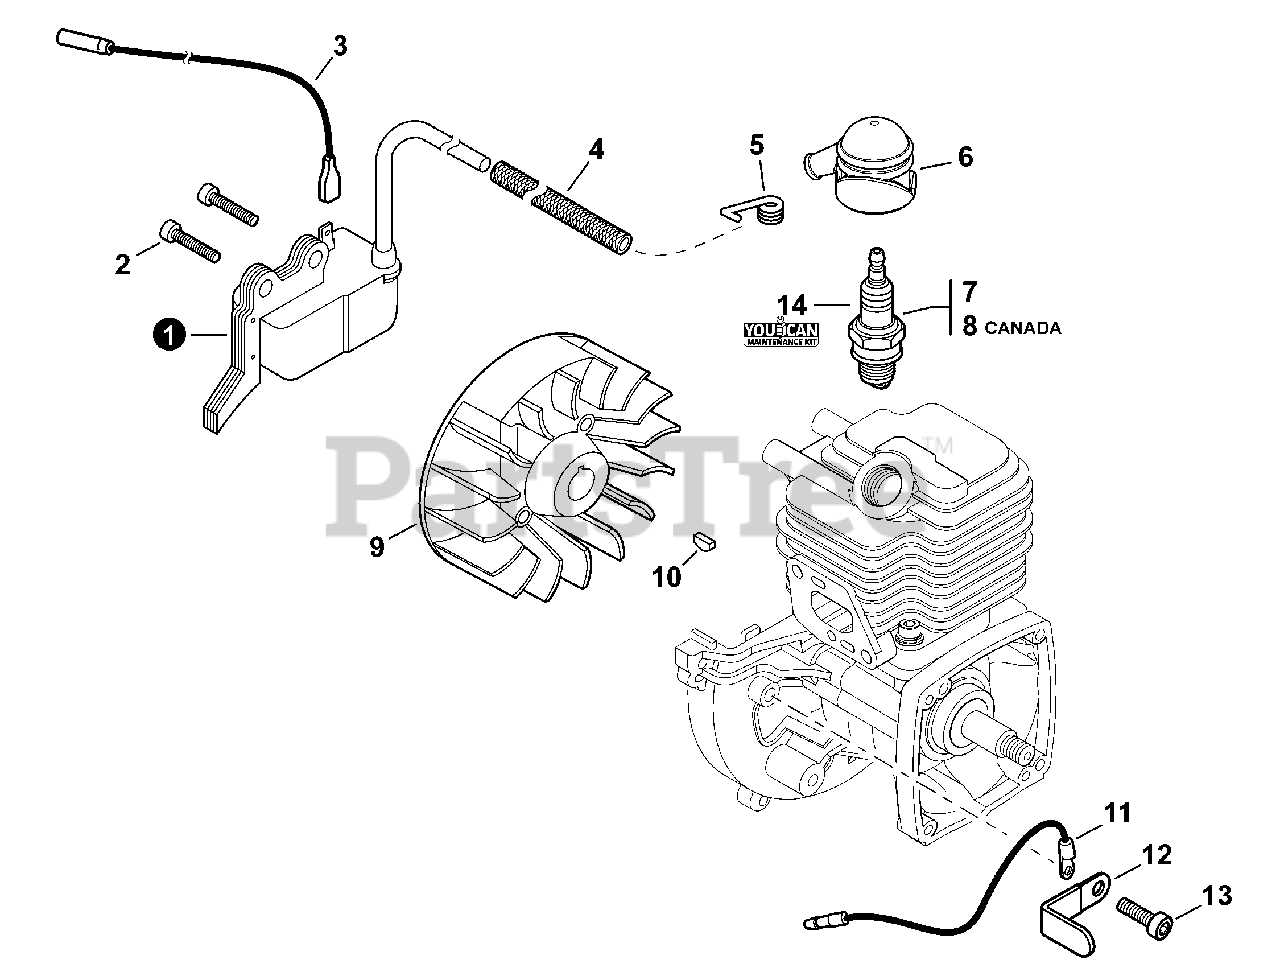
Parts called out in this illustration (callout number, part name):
1	COIL, IGNITION
2	BOLT, TORX 4×20
3	LEAD - IGNITION L= 210
4	TUBE, INSULATOR
5	TERMINAL, SPARK PLUG
6	CAP, SPARK PLUG
7	SPARK PLUG - BPM8Y
8	SPARK PLUG - BPMR8Y
9	FLYWHEEL
10	KEY, WOODRUFF
11	LEAD - GROUND
13	BOLT, TORX 5×10
14	TUNE-UP KIT - YOUCANT
